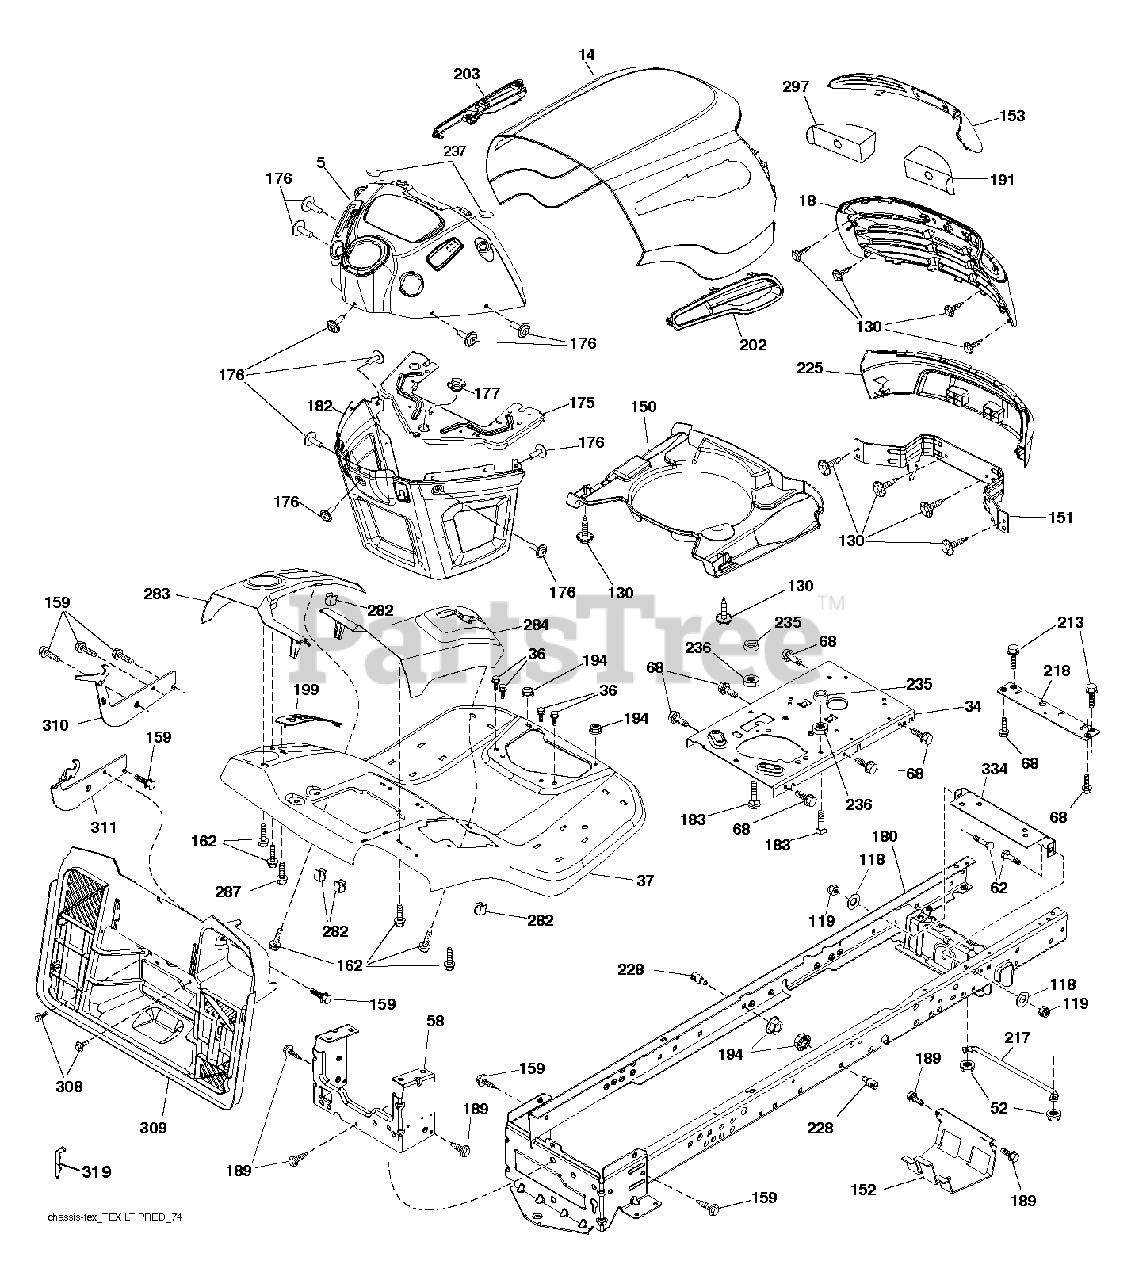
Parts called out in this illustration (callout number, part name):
36	SCREW 5/16"
52	LOCKNUT
58	DRAWBAR UPPER 2PC SMALL FENDER
119	LOCKNUT
130	SCREW.#10 X 0.750.BOS THREAD
151	BRACKET.PIVOT.ALPHA.LT
152	SHIELD BROWNING
159	SCREW, 3/8-16X3/4
162	SCREW.HI-LO.CONSOLE
175	CROSSMEMBER
176	SCREW.#10-24X5/8.RN.QU
177	BUSHING STEERING
182	DASH.LWER.PREDATOR/HUSQ.LT
183	BOLT.5/16-18X1-1/4 FULL THD
189	SCREW
191	INSERT.REFLECT.PREDATOR.LT.RH
194	NUT LOCK HEX FLANGE 5/16-18
213	BOLT
217	ROD.PIVOT.HOOD
218	X-PIECE.HOOD.STOP.NON/
228	STUD.FASTNER.W/ANTI-ROTATE
235	SPACER FENDER
236	NUT.CENTERLOCK.5/16-
237	PLUG.MOUNT.CARGO.BLK
282	CLIP.RETAINER.CONSOLE.LT.HUSQ
297	REFLECTOR.INSERT.PRED.LH.LT
308	BOLT, 5/16-18 X 1 3/4
